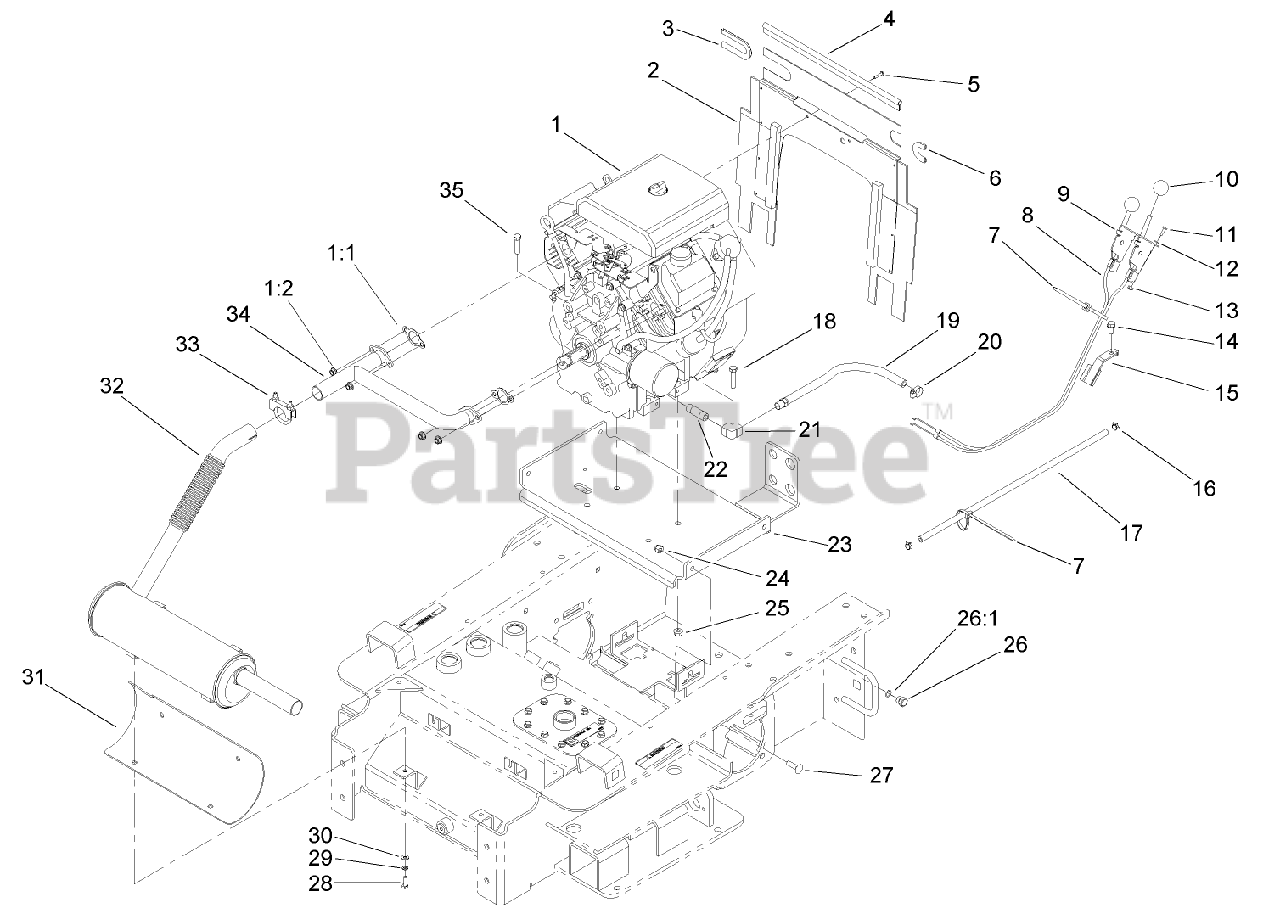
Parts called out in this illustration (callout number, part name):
1:1	GASKET-EXHAUST
1:2	NUT-HF
2	Engine Baffle ASM
3	SEAL-STRIP, 6.5 INCH
4	Seal-Strip, 16 INCH
5	SCREW-PPH
6	SEAL-STRIP, 3 INCH
7	TIE-CABLE
8	CONTROL ASM
9	CABLE-THROTTLE/CHOKE
12	WASHER-FLAT
13	NUT-LOCK, NI
14	SCREW-HWHTF
15	GUIDE-CABLE
16	CLAMP-HOSE
17	HOSE-FUEL
18	SCREW-HH
19	OIL HOSE ASM
20	CLAMP-HOSE
21	ELBOW-90 DEG
22	NIPPLE
23	ENGINE MOUNTING PLATE ASM
24	NUT-LOCK, NI
25	NUT-HF
26	PLUG-HH
26:1	O-RING
27	SCREW-CARR
28	SCREW-HH
29	WASHER-LOCK
30	WASHER-FLAT
31	SHIELD-HEAT, MUFFLER
32	MUFFLER
33	CLAMP-MUFFLER
34	MANIFOLD-CROSSOVER
35	BOLT-HH
